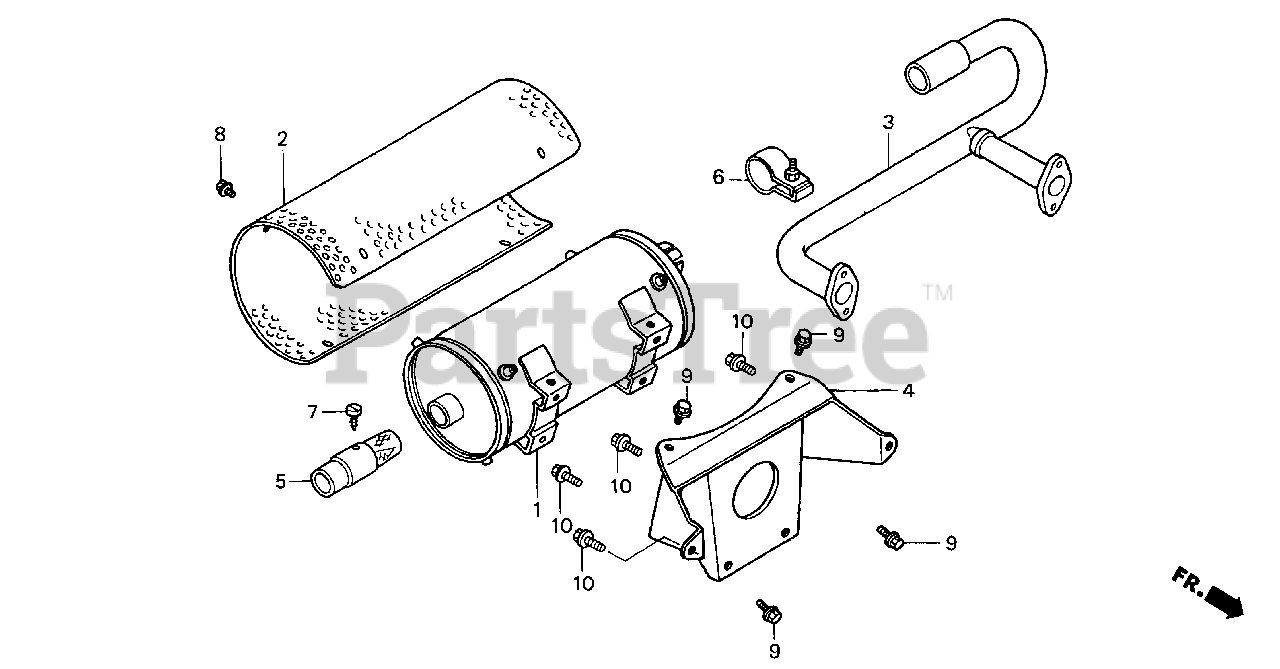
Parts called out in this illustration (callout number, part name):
1	MUFFLER (HIGH)
2	PROTECTOR, MUFFLER (HIGH)
3	PIPE, EX. (HIGH-R)
4	STAY, MUFFLER (HIGH)
5	ARRESTER, SPARK
6	BAND ASSY.
7	SCREW (NELSON)
8	BOLT, FLANGE (6X8)
9	BOLT, FLANGE (8X14)
10	BOLT, FLANGE (8X20)
